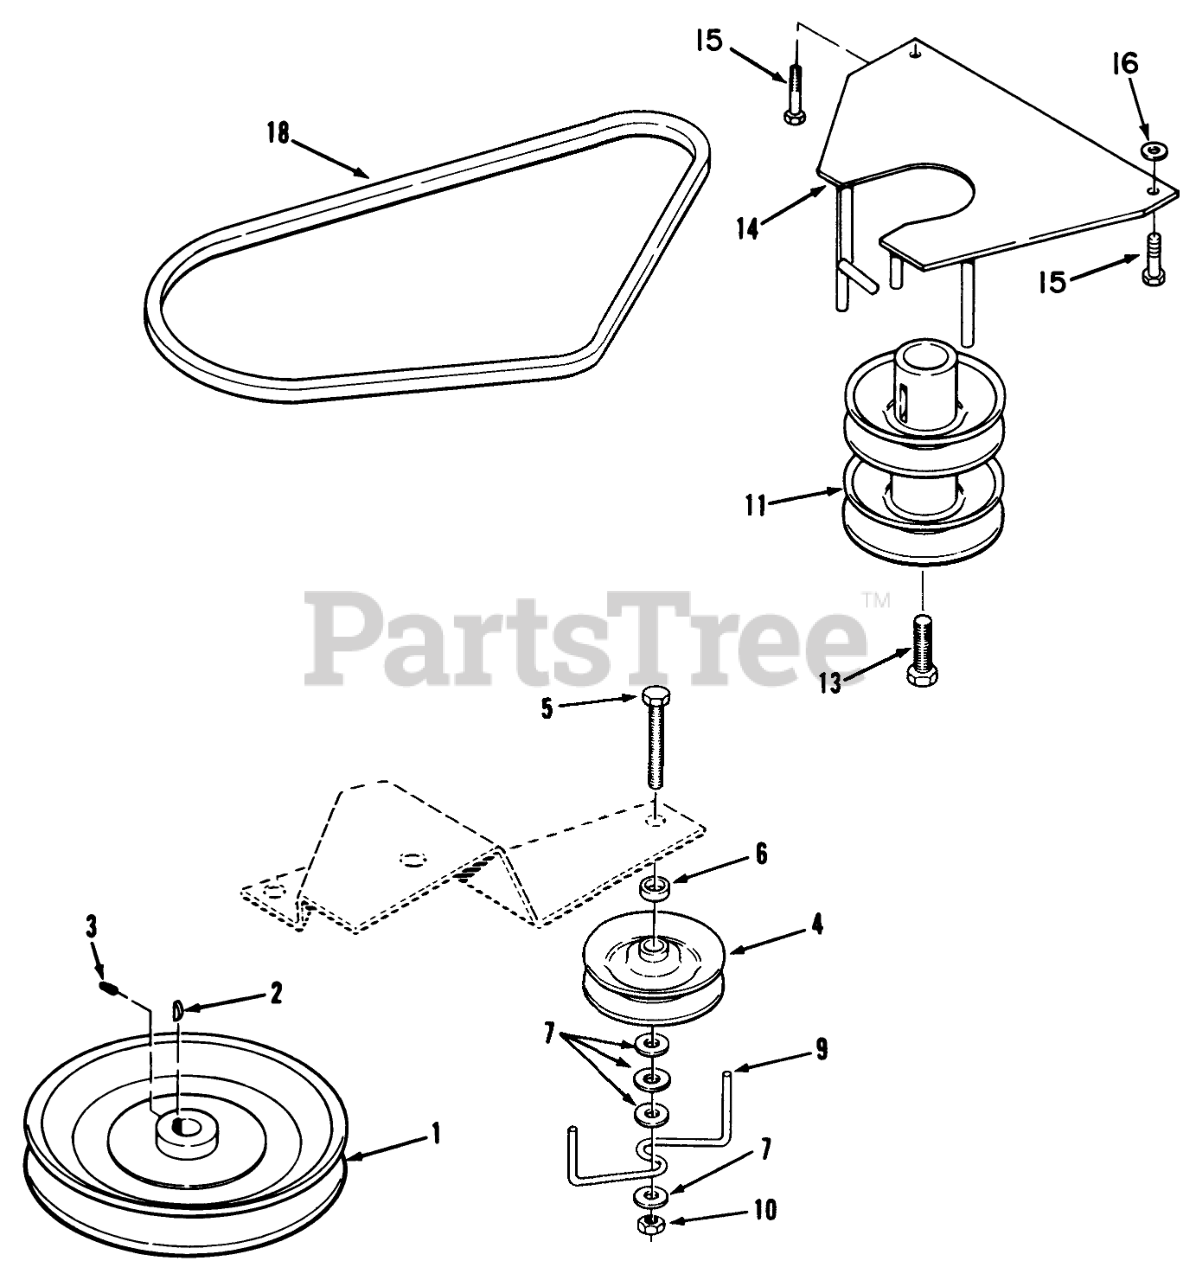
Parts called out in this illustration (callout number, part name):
1	PULLEY TRANSMISSION
2	KEY-HI-PRO
3	SCREW-SQH
4	PULLEY-IDLER V
5	SCREW-HH
6	WASHER-FLAT
7	WASHER-FLAT
9	GUIDE - BELT
10	NUT-HEX, JAM
11	PULLEY-ENGINE
13	HEX HD CAP SCREW
14	ASS'Y-BELT GUIDE R
15	SCREW-HH
16	WASHER-PLAIN
18	BELT-V
